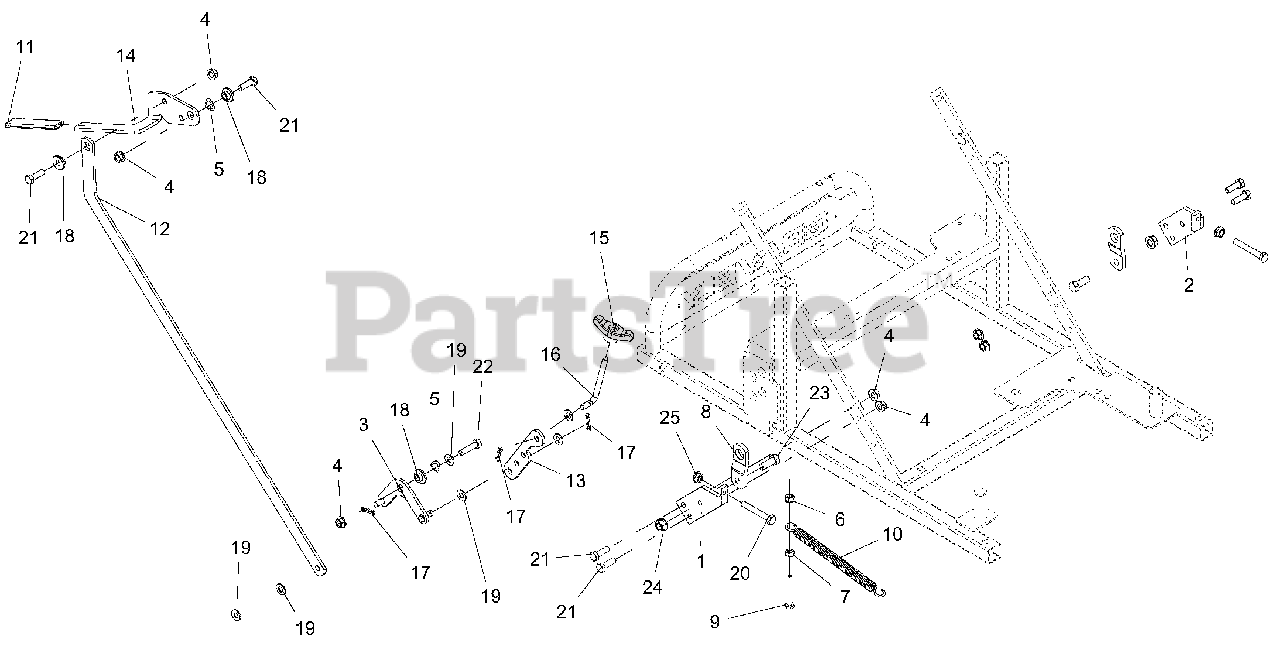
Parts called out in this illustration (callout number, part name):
1	WMT-PIVOT, RH SP FRAME (BLACK)
2	WMT-PIVOT, LH SP FRAME (BLACK)
3	WLDMT, BELL CRANK (BLACK)
4	NUT, LK-TOP-FLG .312-18 YWZC
5	WSHR, WAVE .50X.75X.015 .13FRHT
6	NUT, LK-TOP-FLG .25-20 YWZC
7	NUT-HEX .25-20 YWZC
8	BRKT, SP FRAME PIVOT (BLACK)
9	BLT-HEX .25-20X2.00 GR5 YWZC
10	SPRG, EXTENSION
11	GRIP, MZR/MOMENT SP 7/8X3/4X4
12	BAR, ENGAGEMENT LEVER CONN. (BLACK)
13	BRKT, ENGAGE, ADJ (BLACK)
14	LEVER, SP ENGAGEMENT (BLACK)
15	KNOB, WING .31-18 UNC NYL/TALC
16	THDED ROD .31-18X3.0THD YZ
17	PIN-HAIR, ENDRIES #25 YWZC
18	BSHG, FLG .32X.500.344X.880
19	WSHR-FL-STL.344X.688X.065YWZC
20	HHCS 5/16-18 X 2-1/4 FULL THD
21	BLT-HEX .31-18X1.00 GR5 YWZC
22	BLT-HEX .31-18X1.25 GR5 YWZC
23	BLT-HEX .38-16X1.00 GR5 YWZC
24	NUT, LK-TOP-FLG .38-16 YWZC
25	@NUT-SPNLK-FLG .312-18 YWZC
